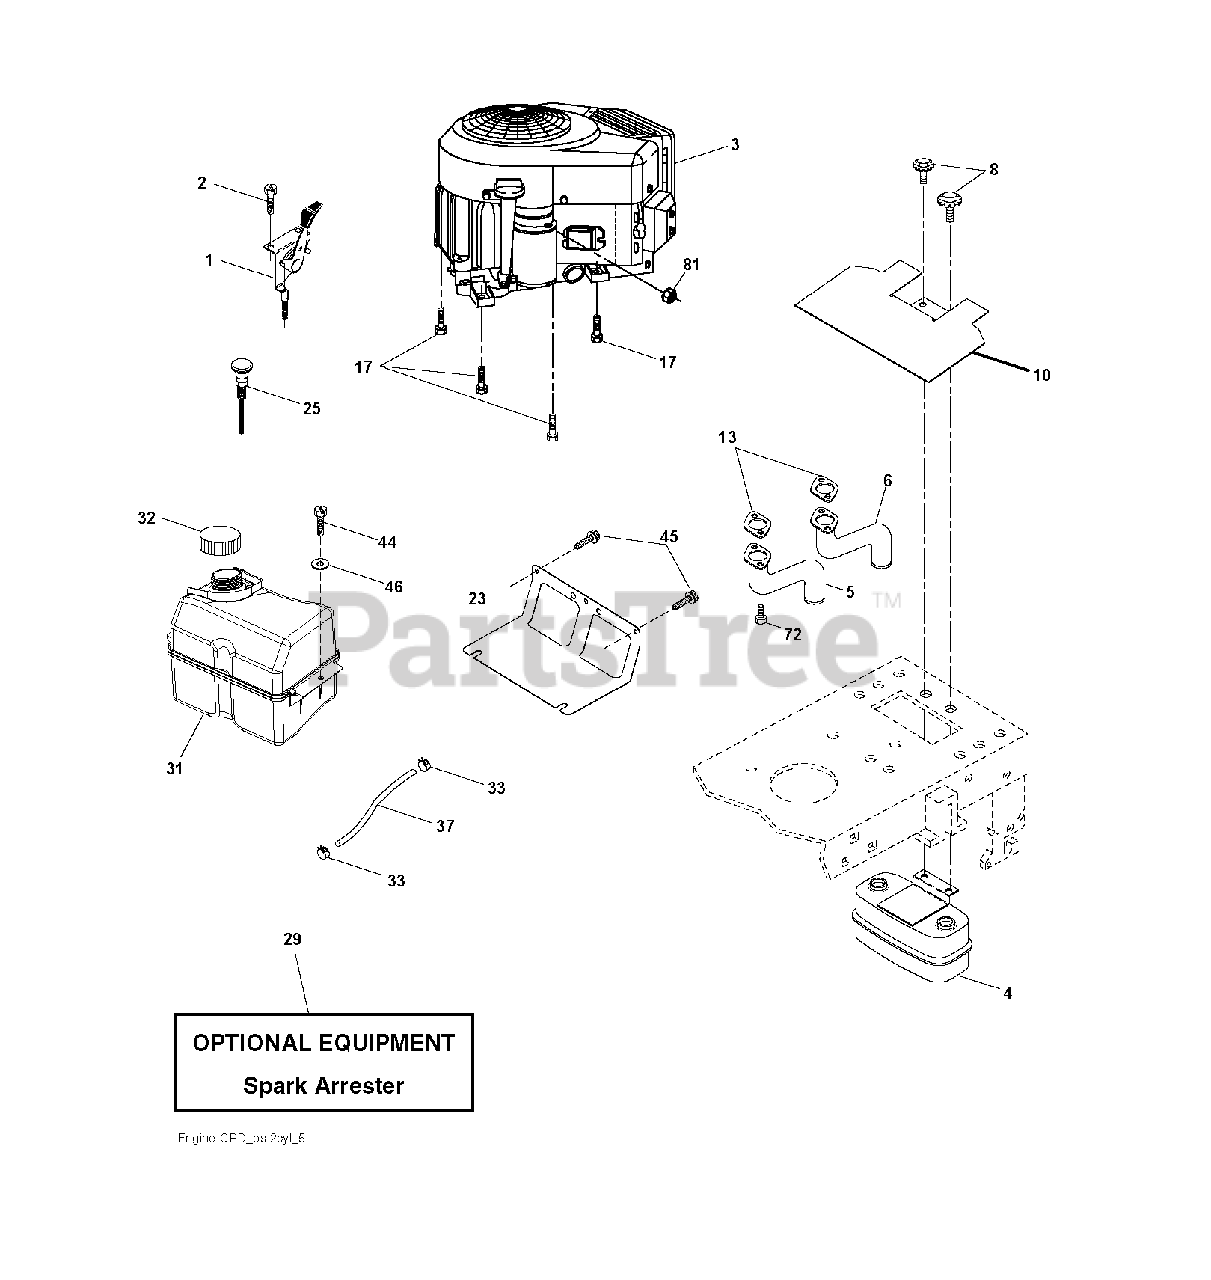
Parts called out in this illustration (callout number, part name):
1	CONTROL, THROTTLE
2	SCREW
4	MUFFLER.TWIN.CYL.LOW.TONE
5	TUBE MANIFOLD LH
6	EXHAUST TUBE RH
8	BOLT, 5/16-18 X 1 3/4
10	RP SHIELD HEAT MUFFLER
13	GASKET.MUFFLER
23	SHEILD.BROWNING.DBR.GUARD
29	ARRESTER SPARK (OPTIONAL)
32	FUEL CAP
33	HOSE CLAMP
37	LINE.FUEL.20
44	SCREW HEXWSHR 1/4-20X3/4
45	SCREW, 3/8-16X3/4
72	SCREW.SOCKET.HEAD.5/16-18
78	SCREW.3/8-16
81	NUT
